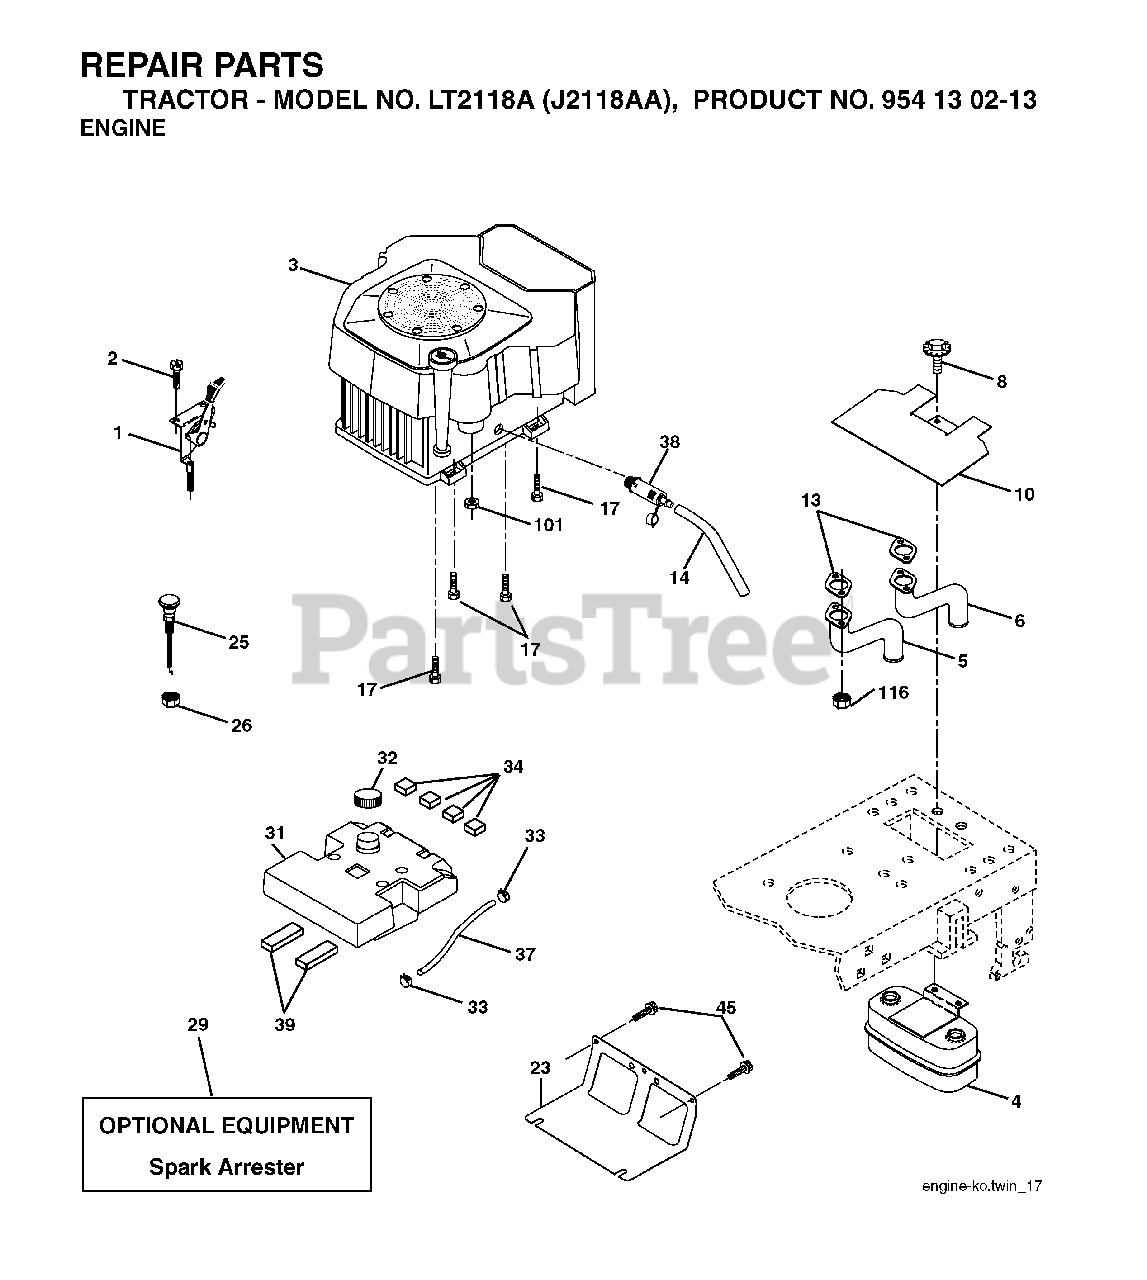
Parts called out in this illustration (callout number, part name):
1	CONTROL.THROTTLE.KAWA
2	SCREW
4	MUFFLER.TWIN.CYL.LOW.TONE
5	PIPE-EXHAUST LH
6	PIPE-EXHAUST RH
8	BOLT, 5/16-18 X 1 3/4
10	RP SHIELD HEAT MUFFLER
13	GASKET.EXHAUST.KOHL.CV18-CV26
14	TUBE, DRAIN OIL ASM.
16	LOCKWASHER
23	SHEILD.BROWNING.DBR.GUARD
25	CHOKE CONTROL
26	NUT KEPS 3/8 - 24 UNF
29	ARRESTER SPARK (OPTIONAL)
31	TANK.FUEL(3.5.GAL)
32	FUEL CAP
33	HOSE CLAMP
34	PAD-SPACER LT
38	PLUG DRAIN OIL EASY
39	PAD IDLER TI
45	SCREW, 3/8-16X3/4
101	FLANGE NUT
116	NUT.HEX.FLANGE.TOPLOCK
